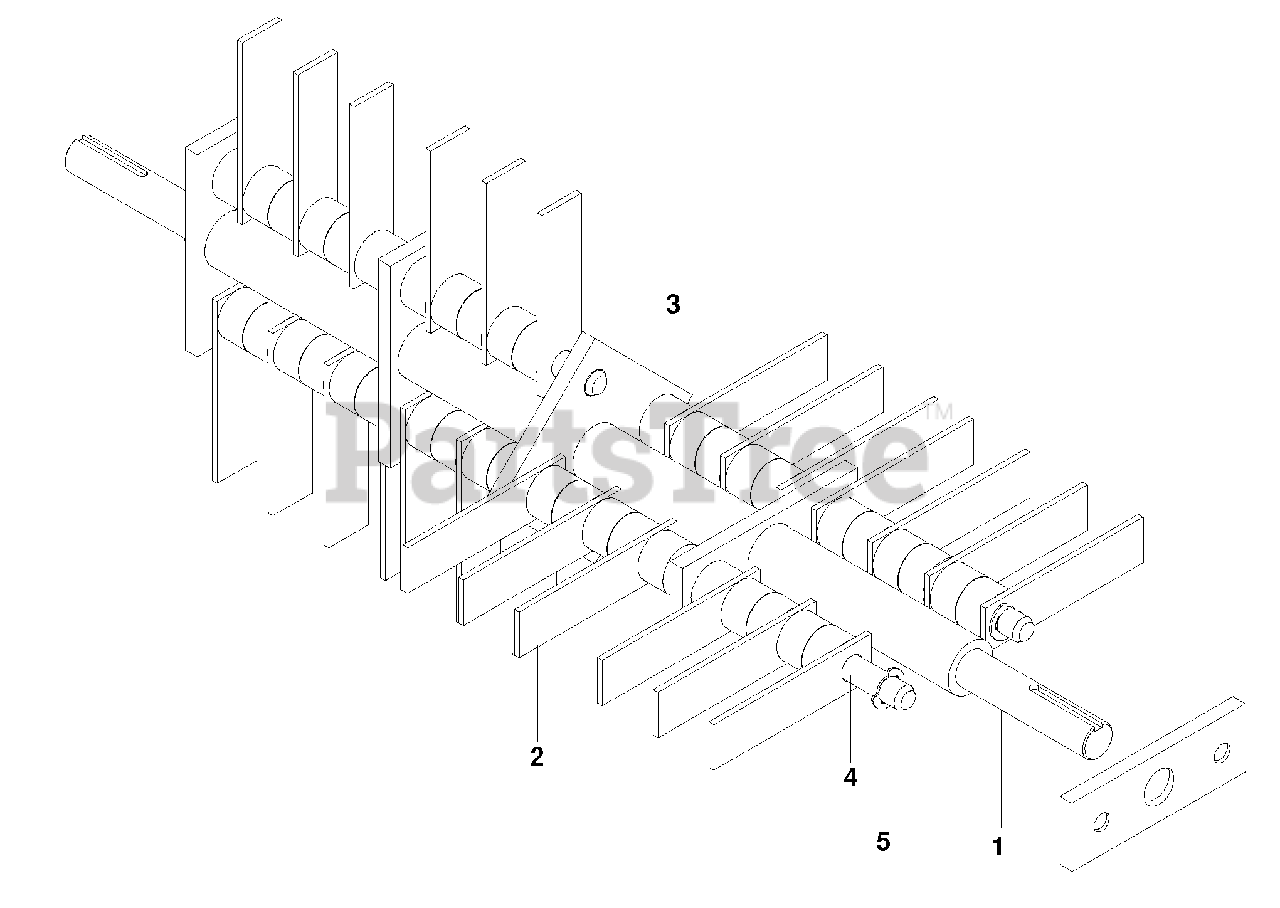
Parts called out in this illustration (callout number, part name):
3	SPACER 22"
4	BLADE SHAFT 22"
5	E-RING 1/2"
